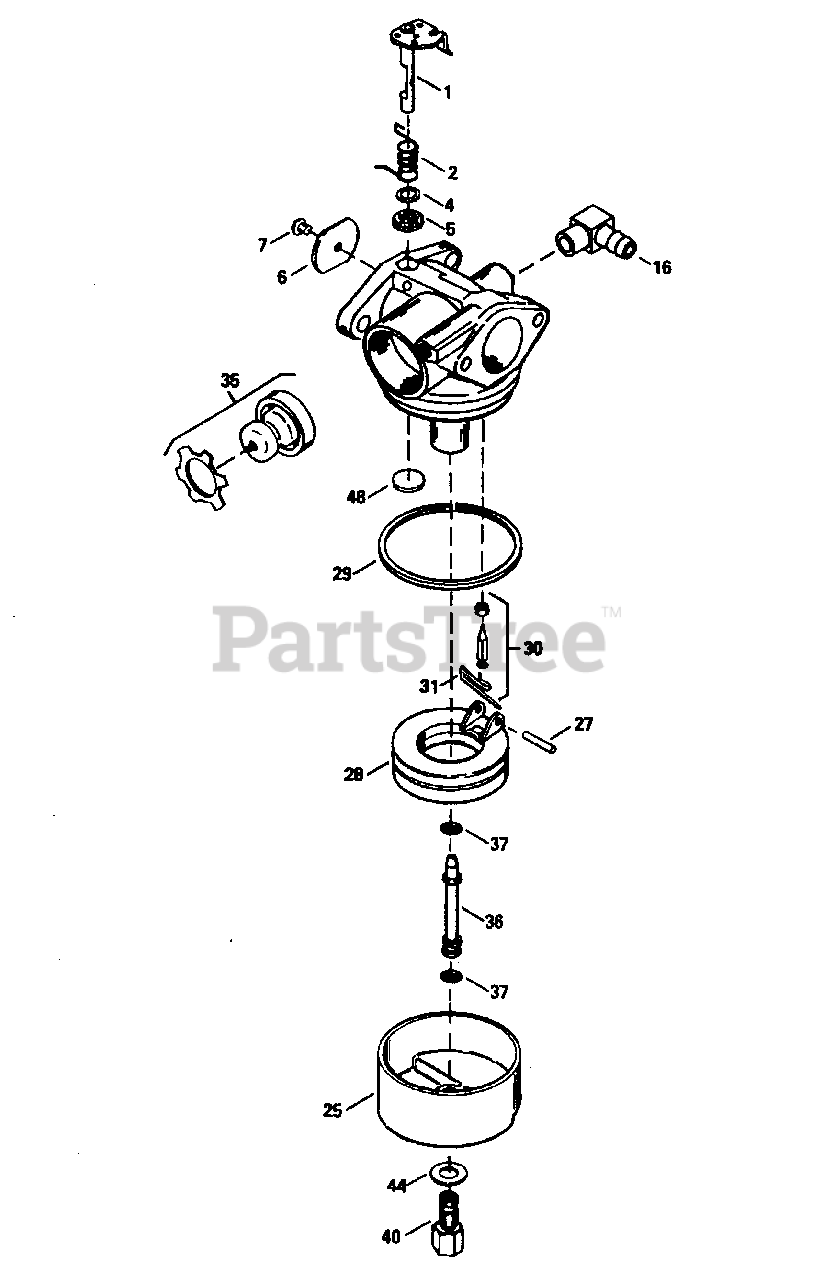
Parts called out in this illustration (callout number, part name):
1	Throttle Shaft & Lever Assembly
2	Throttle Return Spring
4	* Dust Seal Washer
5	* Dust Seal (Throttle)
6	Throttle Shutter
7	* Shutter Screw
16	Fuel Fitting
25	Float Bowl
27	* Float Shaft
28	Float
29	* Float Bowl "O" Ring
30	* Inlet Needle, Seat, & Clip (Incl. 31)
31	Spring Clip
35	Primer Bulb/Retainer Ring
36	Main Nozzle Tube
37	* "O" Ring, Main Nozzle Tube
40	High Speed Bowl Nut
44	Bowl Nut Washer
48	* Welch Plug, Atmospheric Vent
60	Repair Kit Incl. items marked PK inn otes
